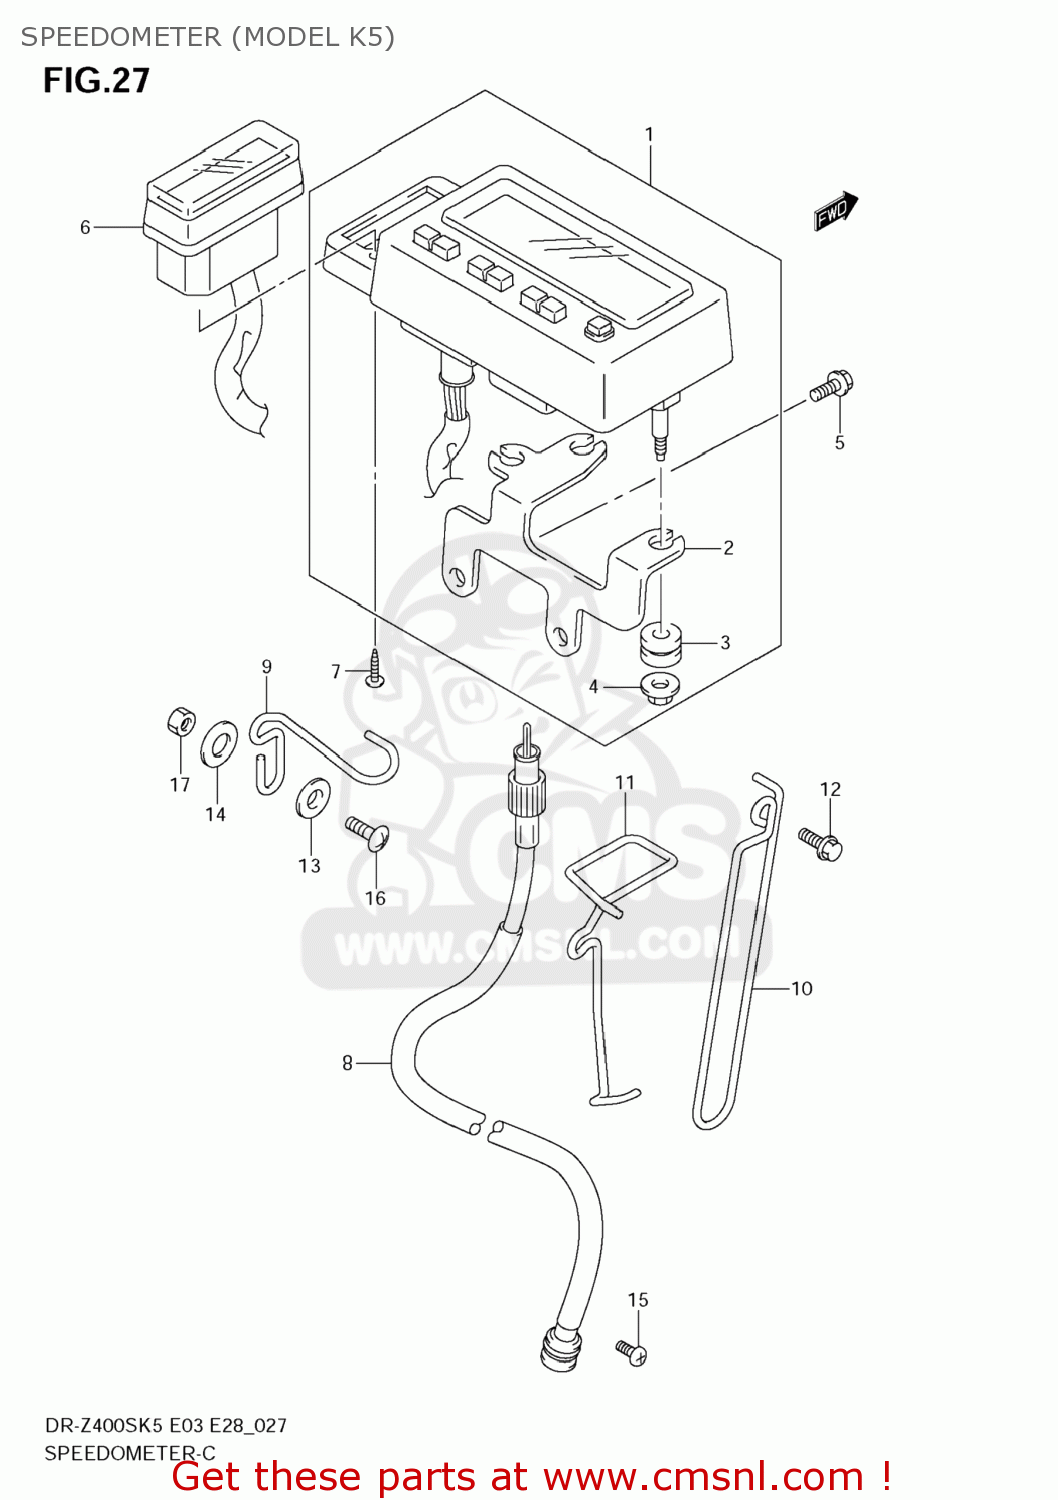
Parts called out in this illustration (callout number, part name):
1	SPEEDOMETER ASSY
2	BRACKET
3	CUSHION,METER
4	NUT
5	BOLT
6	BOX ASSY,PILOT LAMP
7	SCREW
8	CABLE ASSY,SPEEDOMETER
9	GUIDE,SPEEDOMETER CABLE
10	GUIDE,METER CABLE NO.2
11	GUIDE,SPEEDOMETER CABLE NO.3
12	BOLT(6X20)
13	WASHER(6.5X18X1.6)
14	WASHER
15	SCREW
16	SCREW
17	NUT
